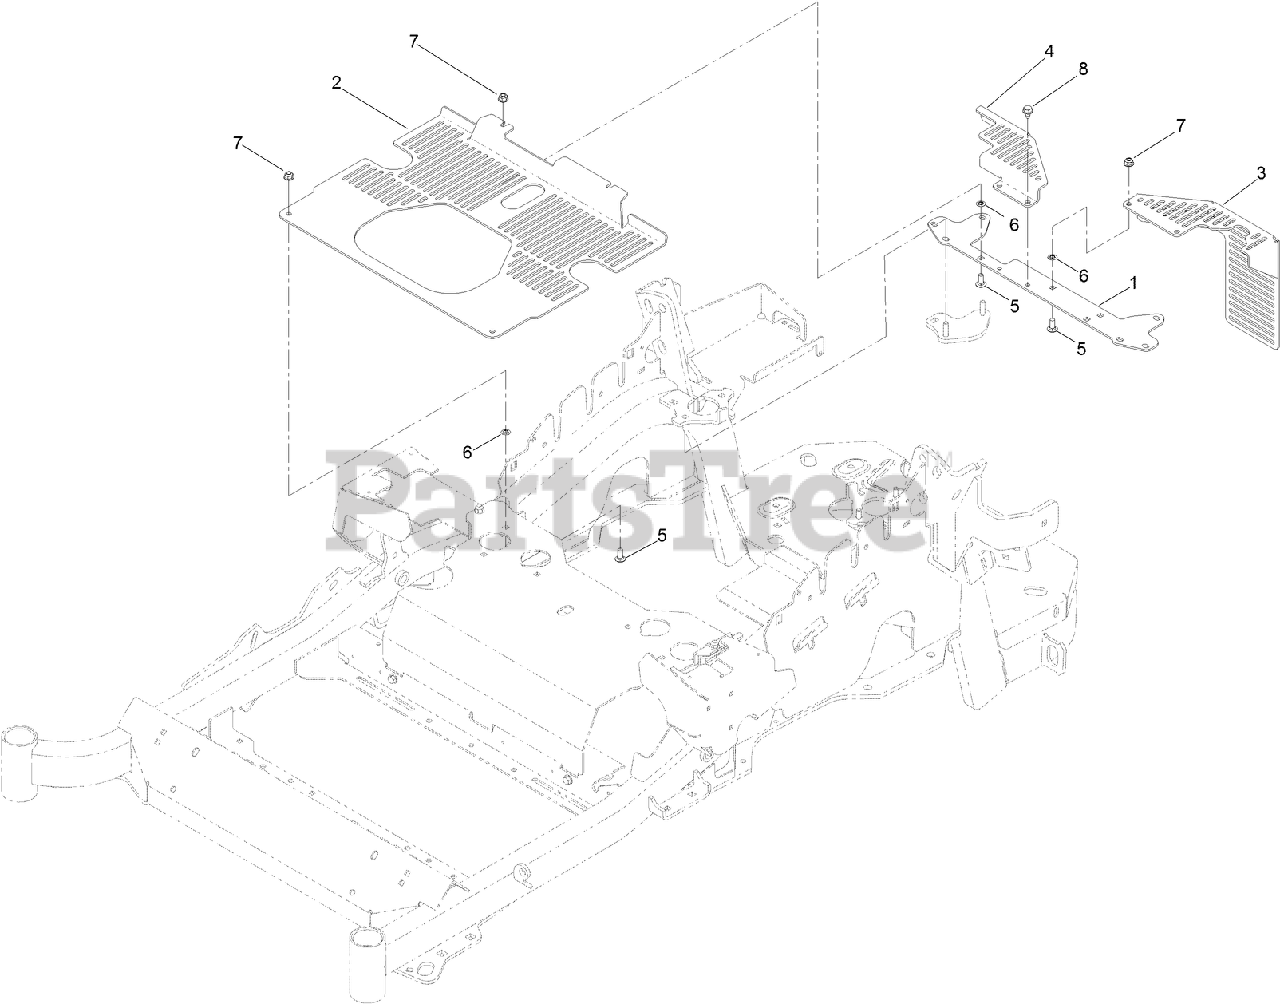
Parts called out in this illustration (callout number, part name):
1	PLATE-MOUNTING
2	GUARD-HYDRO
3	GUARD-HYDRO, LEFT REAR
4	GUARD-HYDRO, RIGHT REAR
5	SCREW-CARR
6	RING-RETAINING, BOLT
7	NUT-HF, NI
8	SCREW
